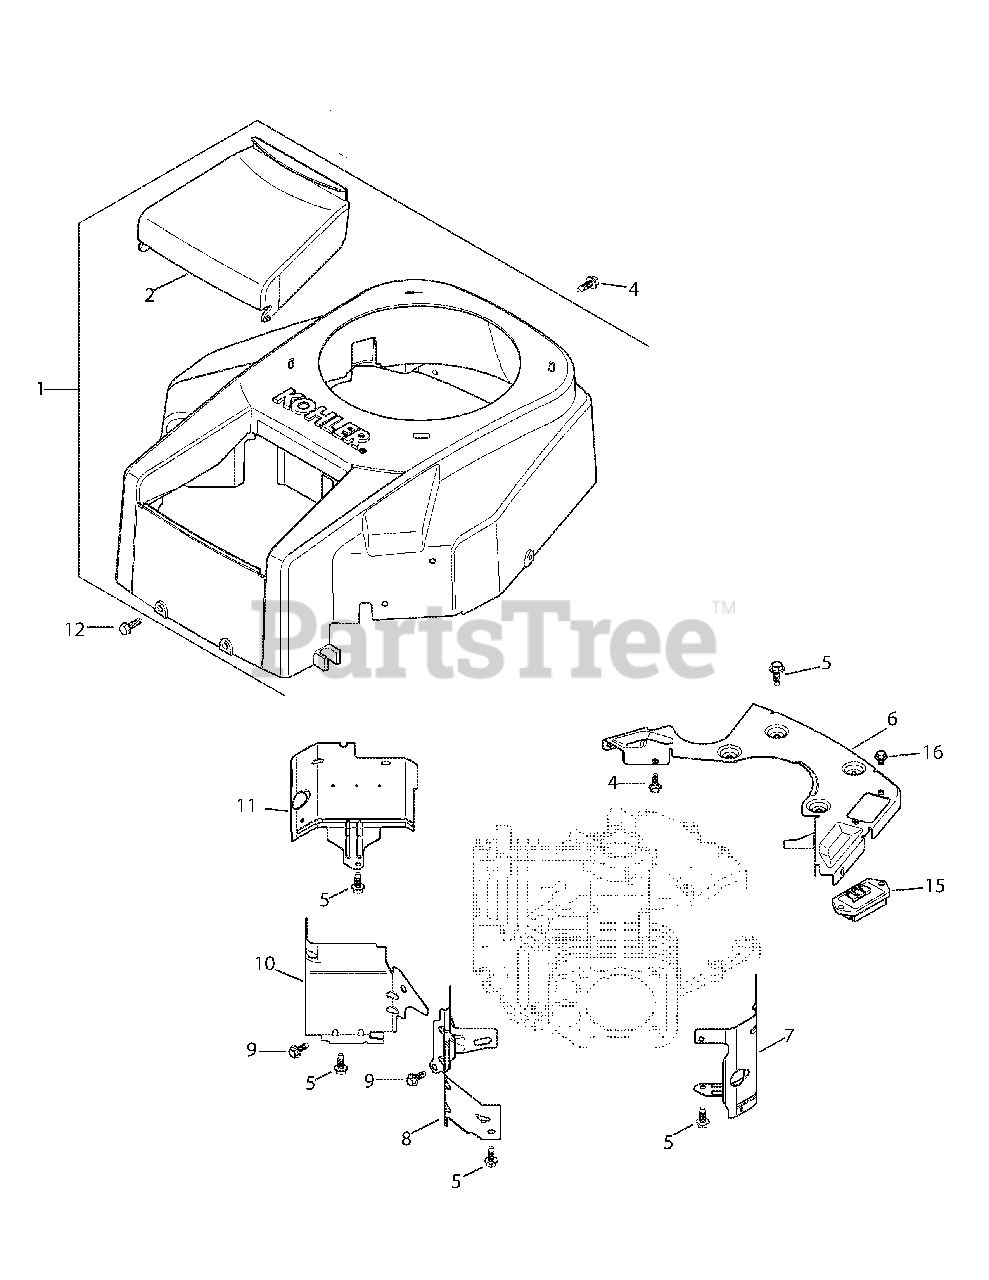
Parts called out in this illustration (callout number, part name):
1	Housing Blower Kit Inc. 2 & KH-41-037-10-S)
2	Air Cleaner Cover
4	Flg. Thd. Frm. Screw, M5 X 0.8 X 16
5	Flg. Thd. Frm. Screw, M6 X 1.0 X 16
6	Backing Plate Kit
7	Cyl. Barrel Baffle - #2 Side
8	Valley Baffle - #2 Side
9	Flg. Thd. Frm. Screw, M5 X .8 X 10
10	Valley Baffle - #1 Side
11	Cyl. Barrel Baffle - #1 Side
12	Tap Screw, M6 X 1.7 X 18
15	Regulator/Rectifier
16	Flg. Thd. Frm. Screw, M6 X 1.0 X 10
